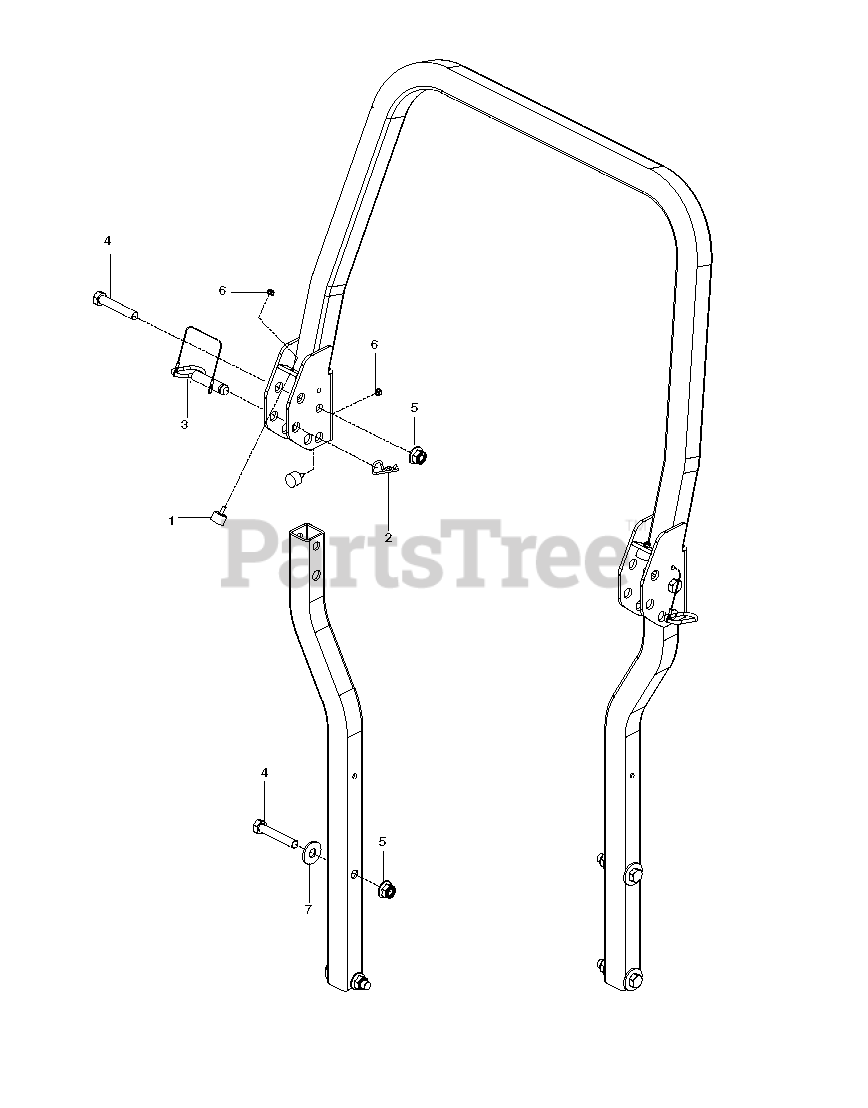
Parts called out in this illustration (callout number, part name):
1	BUMPER, MALE STUD, 1/4-20
3	PIN HAIR .148 X 2-15/16 #210
4	5/8-11 X 3-1/2 HHB GRADE 5
5	NUT 5/8-11 FLG NYLOC ZD
6	RP_NUT 1/4-20 NYLOC
7	WASHER, 5/8 FLAT
